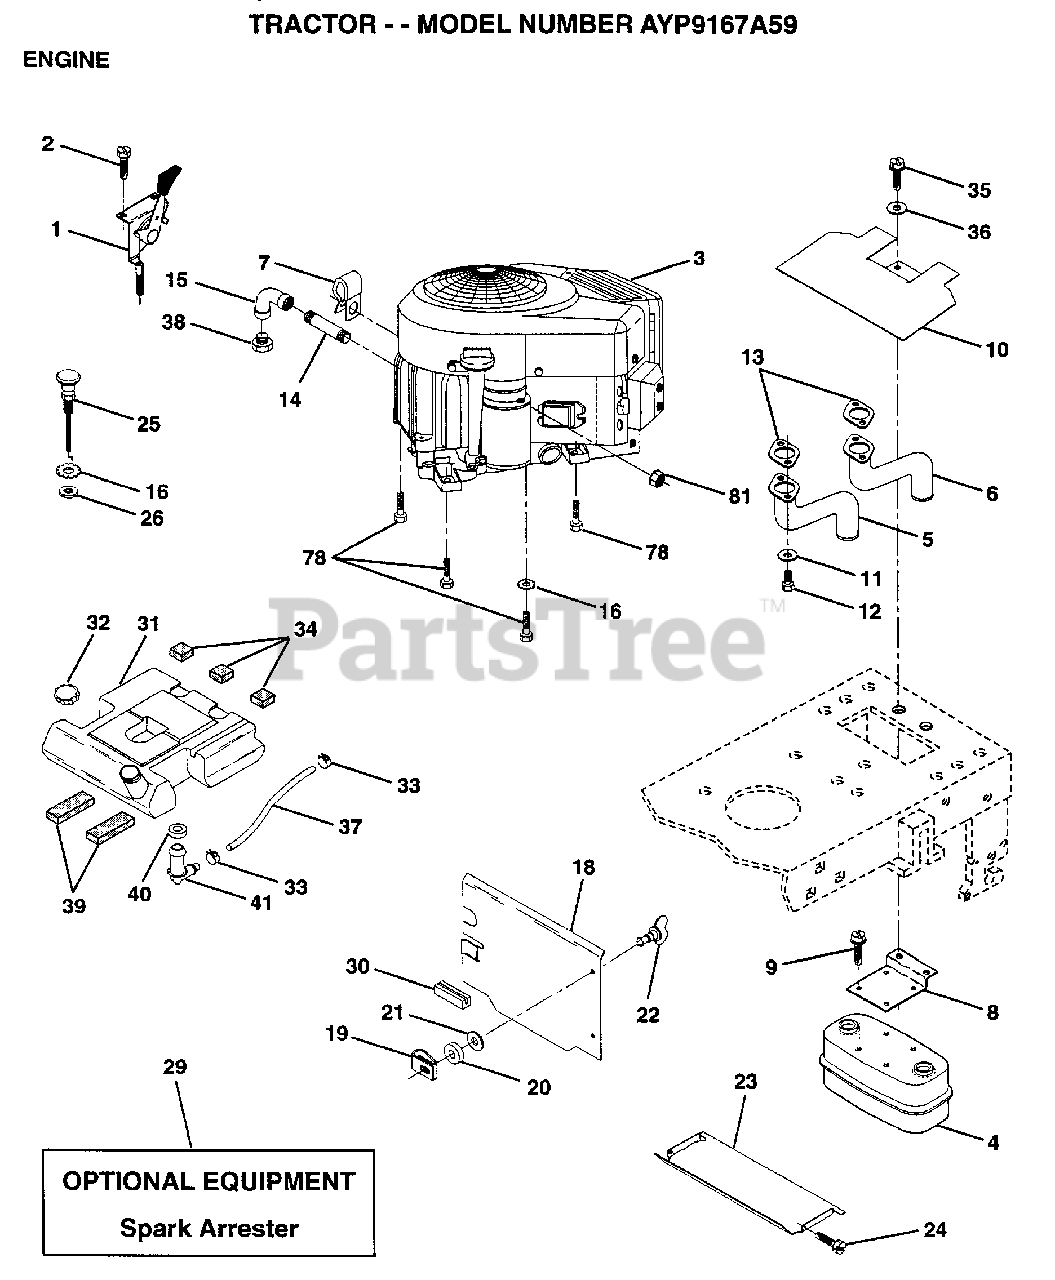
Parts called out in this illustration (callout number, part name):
1	CONTROL THRT 35.5
2	SCREW LT
5	TUBE ASSY EXH LH
6	TUBE ASSY EXH RH
7	CLIP T
8	BRACKET MUFFLER
9	SCREW ST
10	SHIELD.HEAT.
14	PIPE NIPPLE LT
15	ELBOW
16	LOCKWASHER
18	SHIELD HEAT
19	RECEPTACLE LT
20	RETAINER LT
21	WASHER
22	STUD.1/4.TURN
23	HEAT SHIELD
24	SCREW
25	CONTROL.CHOKE.37
32	CAP ASM FUEL
33	HOSE CLAMP
34	PAD-SPACER LT
35	SCREW
36	WASHER
37	FUEL LINE T
39	PAD IDLER TI
40	BUSHING OUTLET T
78	SCREW
81	NUT
